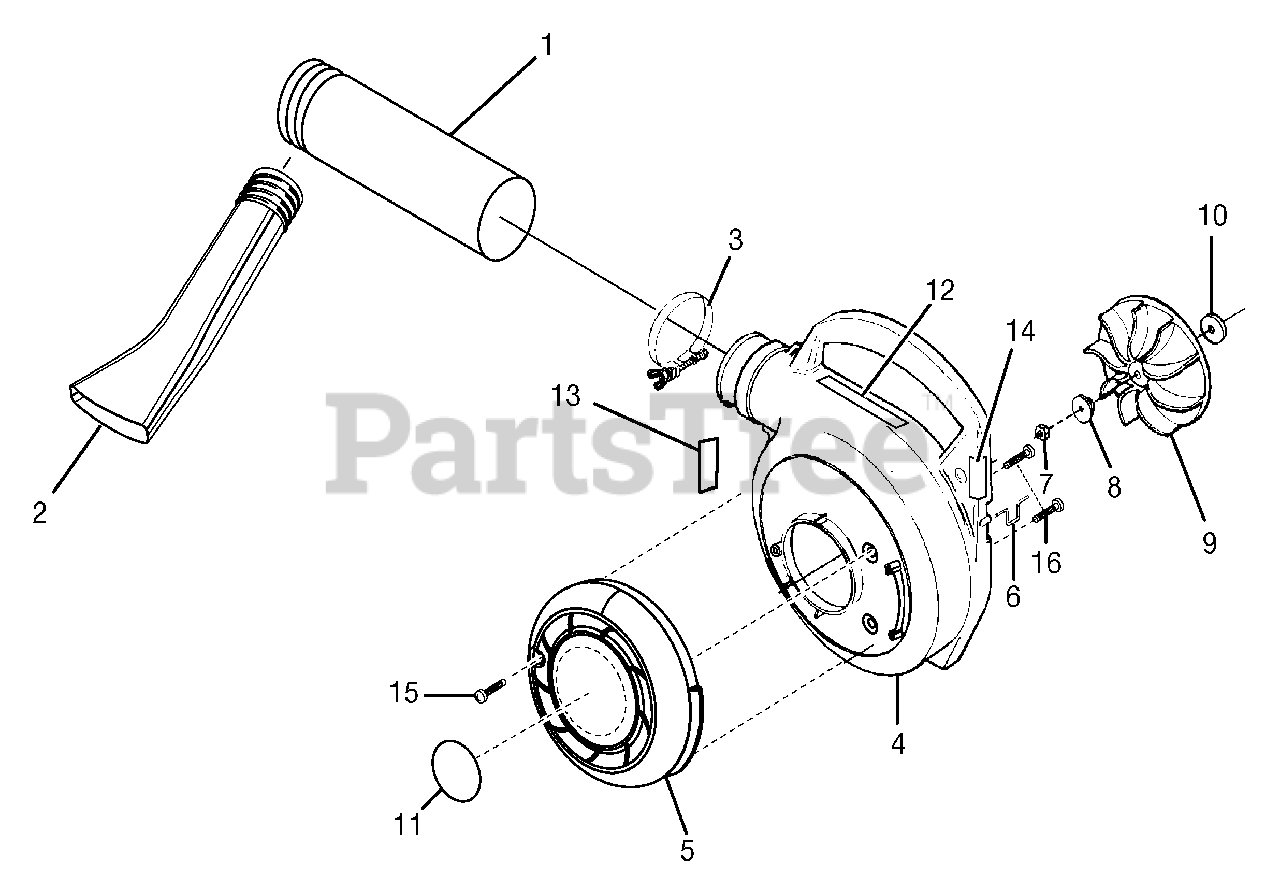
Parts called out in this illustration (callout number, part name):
1	UPPER TUBE
2	LOWER NOZZLE
3	CLAMP WITH FASTENERS
4	OUTER VOLUTE HOUSING
6	WIRE LOOP
7	* HEX NUT (3/8-24)
8	FAN ADAPTER
9	FAN
10	FLAT WASHER
11	DOOR YARD BROOM DECAL
12	WARNING DECAL
13	FAN INTAKE DECAL
14	OUTER VOLUTE DECAL
15	SCREW (1/4-20)
16	SCREW (10-24 X 1/2 in TORX TRUSS HD) 2
